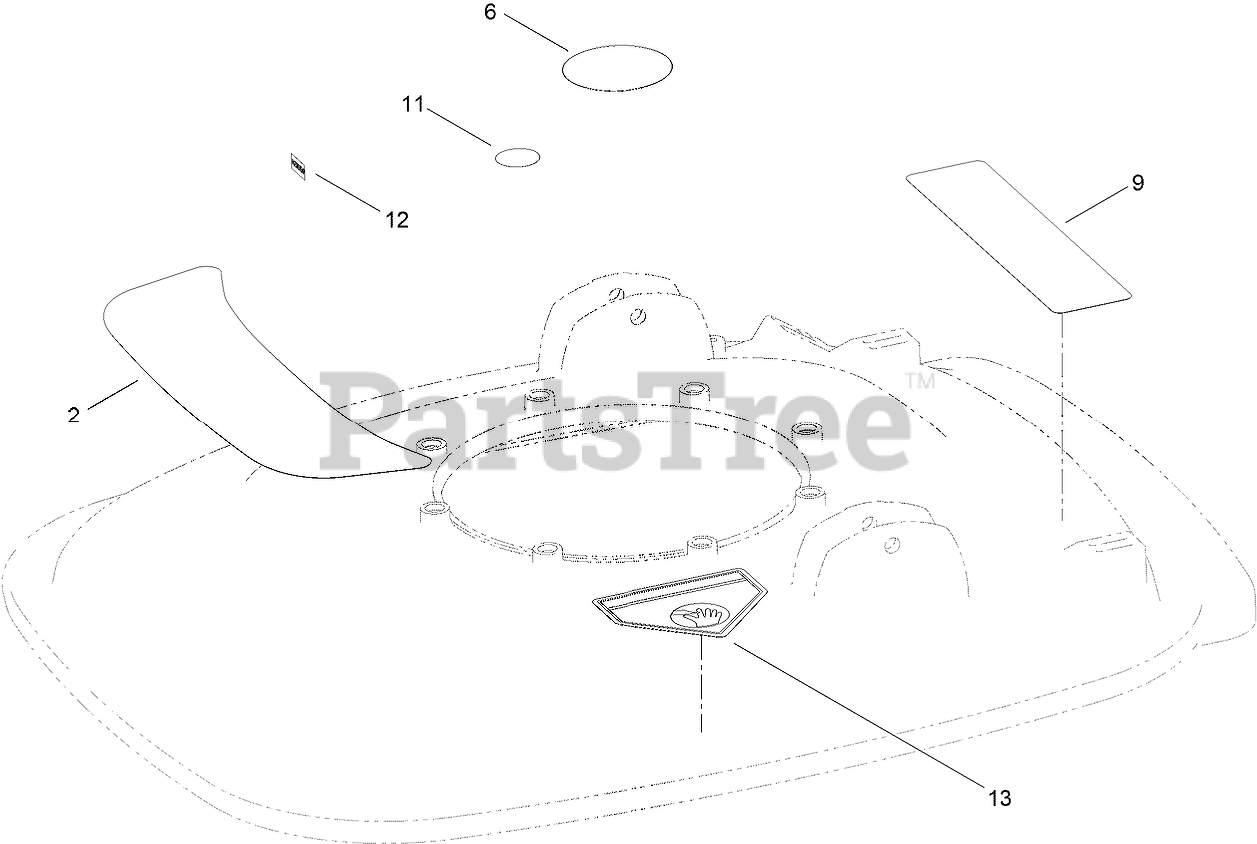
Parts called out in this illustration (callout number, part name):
2	DECAL-HOVER PRO
6	DECAL-ENGINE
9	DECAL-WARNING
11	DECAL
12	DECAL-STOP
13	DECAL-DANGER
